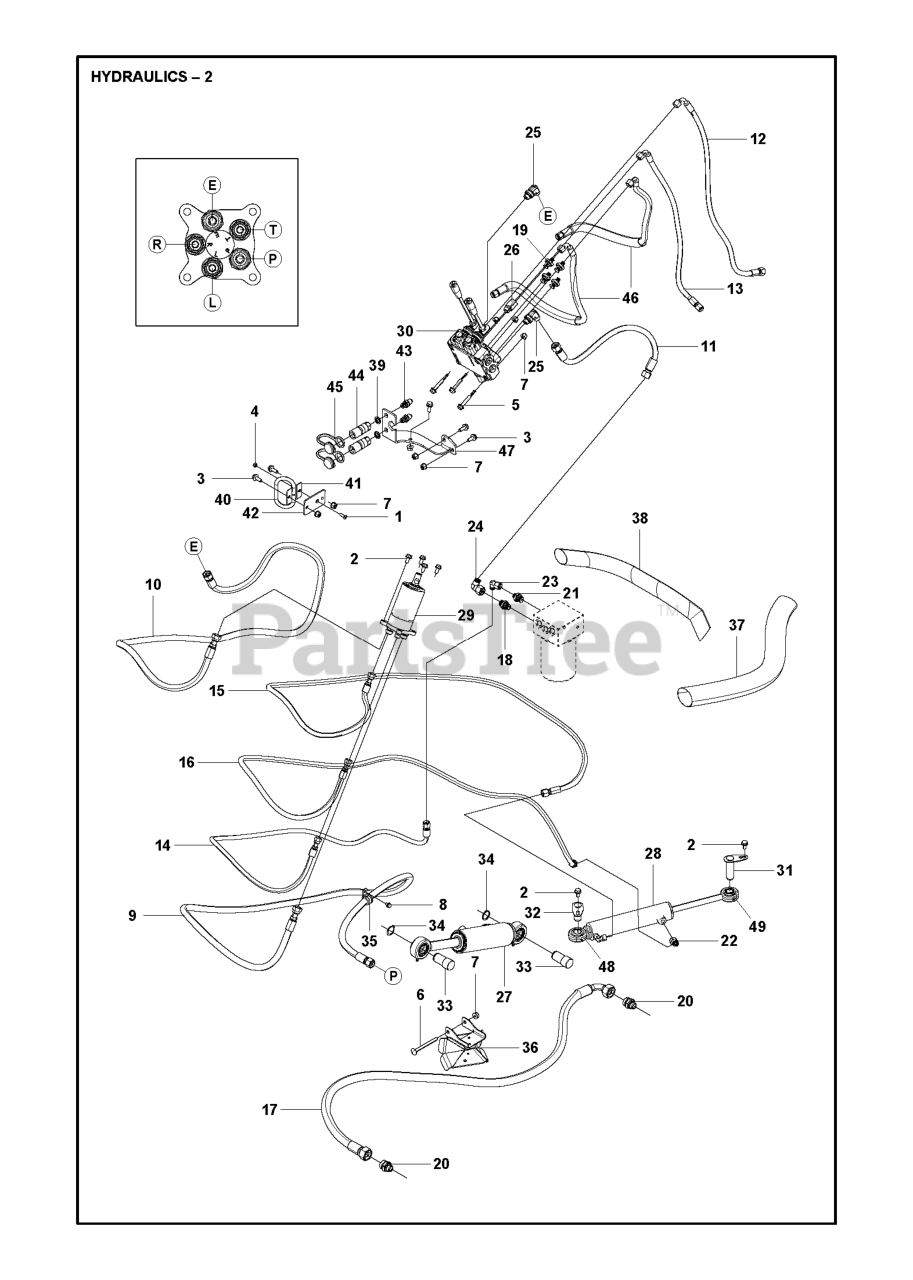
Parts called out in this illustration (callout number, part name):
1	Battery 12 Volt 25 Amp
2	BOLT.HEX.1/4.X.3/4.DICHROMATE
8	BOX.BATTERY.MOUNT.FRONT.LT
16	SWITCH INTERLOOK PUSH-IN
21	HARNESS ASSY LIGHT
24	CABLE.BATT.POS.WIRE.TG.DA SOL
25	CABLE.STARTER.6G.BL/RED.17.5
26	FUSE 20AMP
27	NUT
28	CABLE GROUND 6 GA 21" 90T BLK
29	SWITCH.SEAT.DELTA.OPC.
30	SWITCH.IGN.DELTA.W.LGH.ROS
33	KEY.CHAIN.BLISTER.PACK.GEN.INT
40	HARNESS.IGN.DASH.HUQ/P
41	SCREW
42	TERMINAL COVER
43	SOLENOID.W/BRASS.PLUNGER
46	RP.GUAGE.SRVCMNDR.HRMTR.
50	RP.PTO.SWITCH.8 TERMINAL.BLACK
55	SCREW 5/16"
59	OUTLET.12-VOLT
71	HARNESS-CHASSIS SUB
79	BULB HOLDER ASM.
90	COVER.TERMINAL.BATTERY
91	STRAP.BATTERY.MOUNT.FRONT(2 2)
99	SCREW HEXWSHR 1/4-20X3/4
101	PIGTAIL.MATNLK.NEW.HAR
102	HARNESS PIGTAIL PCH TEX ROS
103	HARNESS PIGTAIL 12V OUTLET
105	REVERSE SWITCH
